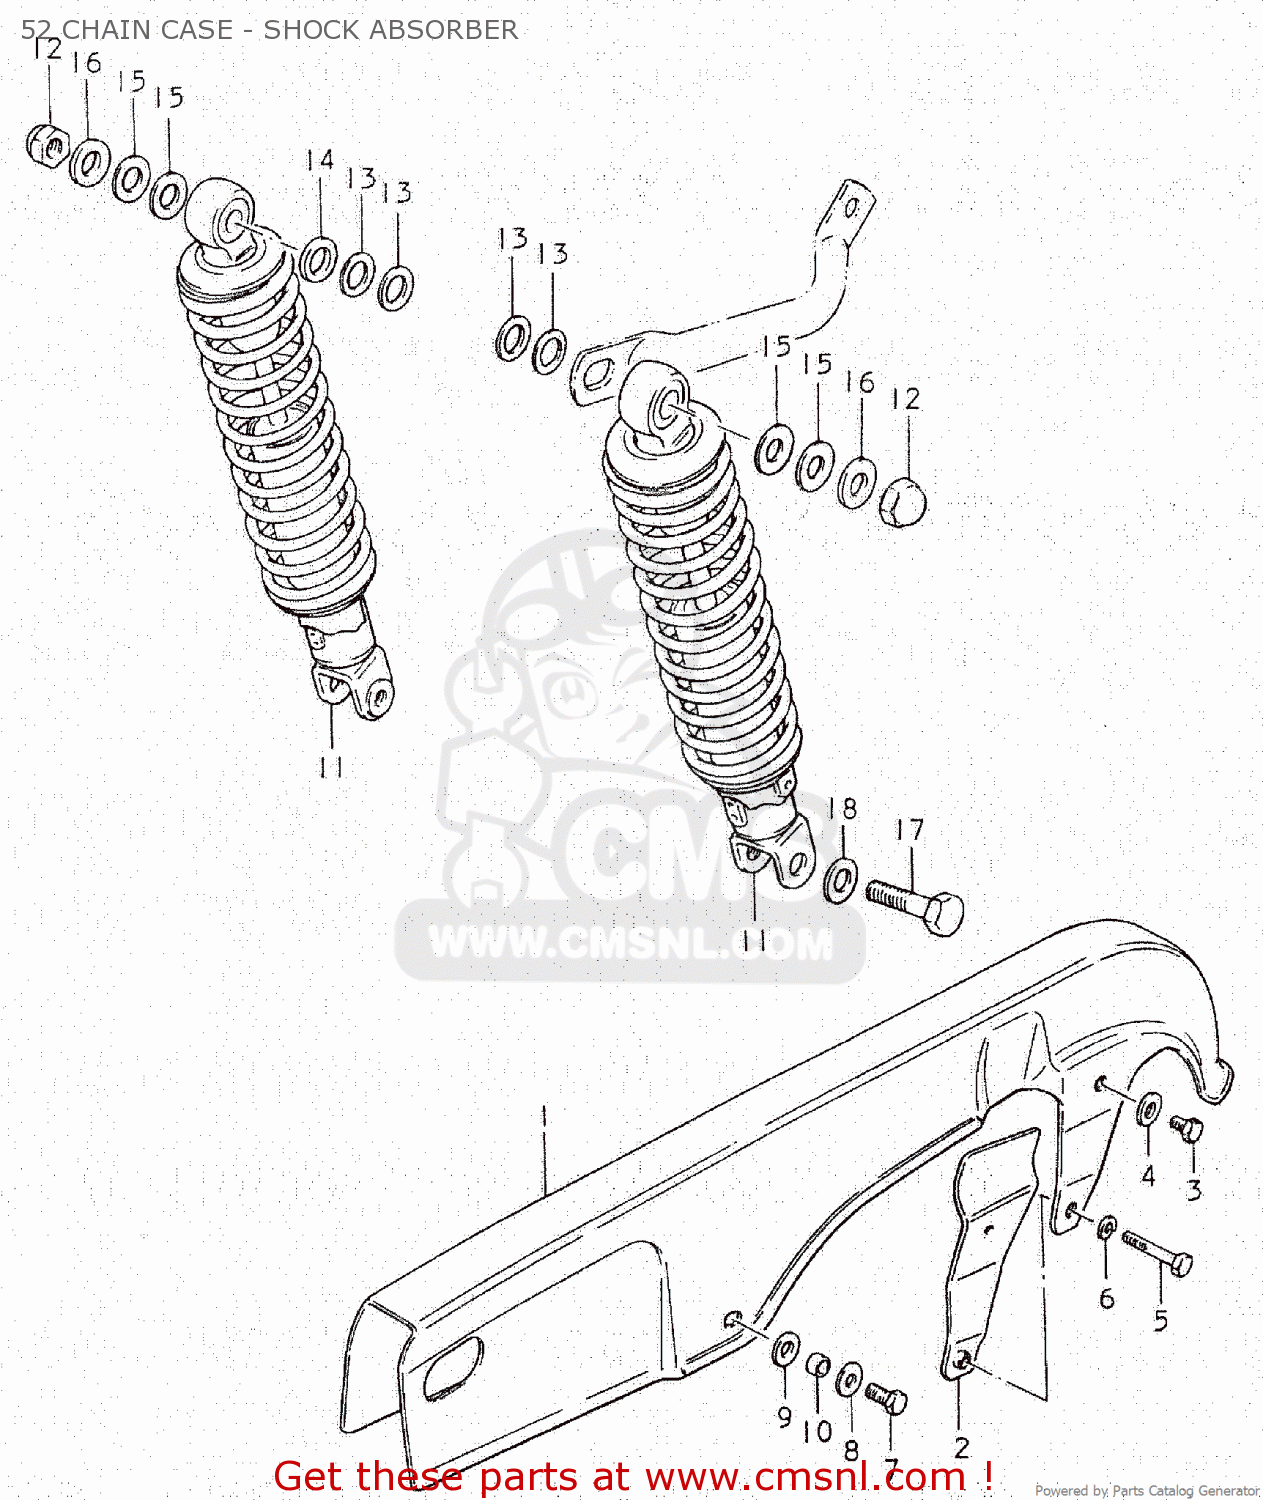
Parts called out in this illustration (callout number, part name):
1	CASE,CHAIN
2	REINFORCEMENT,CHAIN CASE
3	BOLT(6X8)
4	WASHER
5	BOLT
6	LOCK WASHER
7	BOLT
8	WASHER(6.5X18X1)
9	CUSHION
10	SPACER (6.1X8X5.2)
11	ABSORBER ASSEMBLY,REAR SHOCK
12	NUT, LOWER LH
13	WASHER
14	WASHER (12.5X24X3.2)
15	WASHER
16	WASHER(10.5X24X3.2)
17	BOLT(10X36)
18	WASHER
